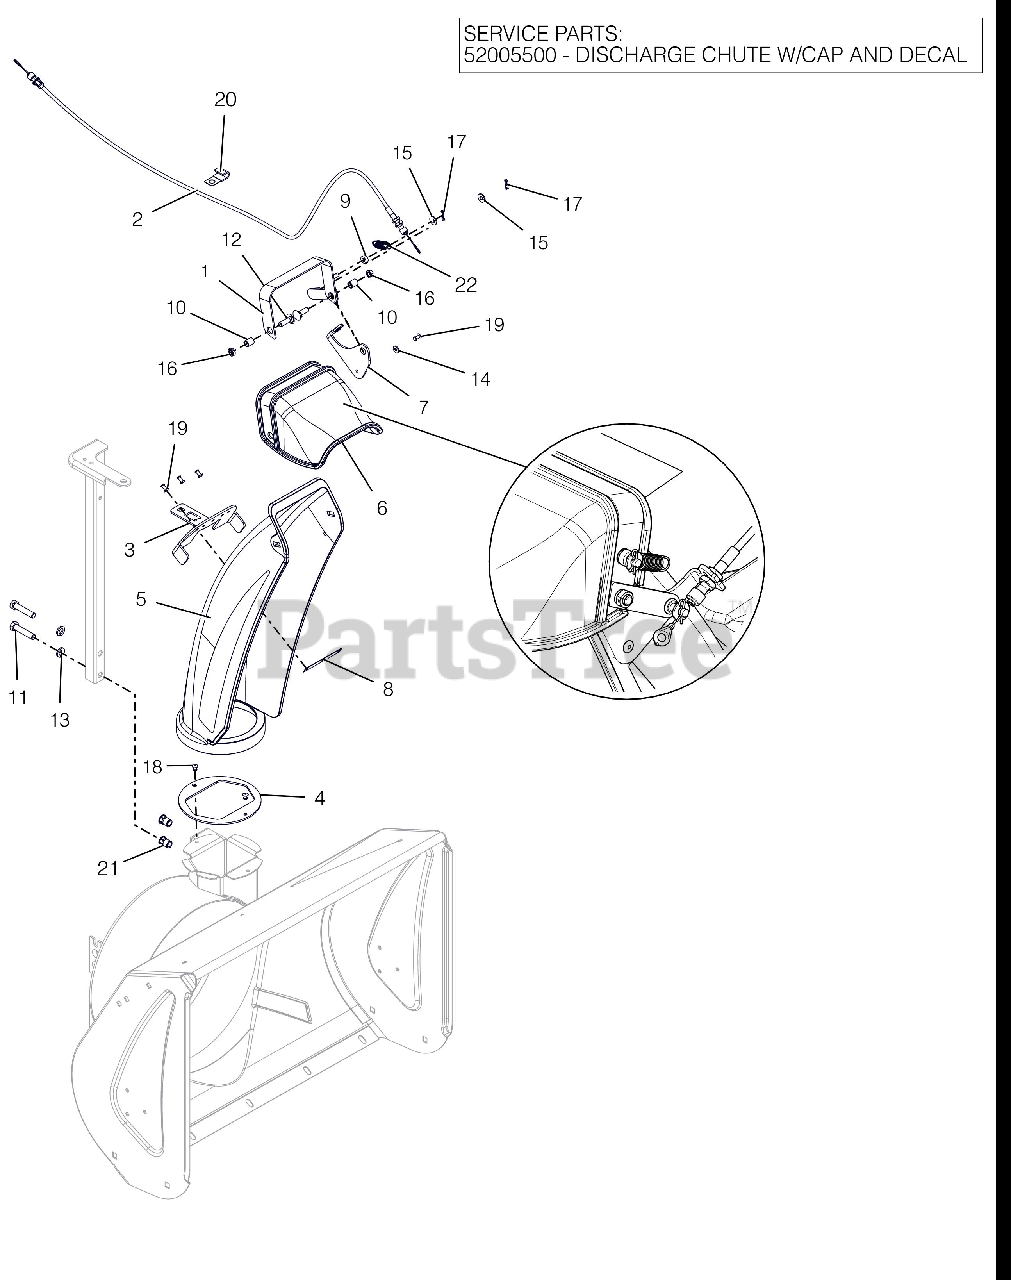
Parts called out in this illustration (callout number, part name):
1	WELDMENT, DEFLECTOR CAP SNOTEK
2	CABLE, DEFLECTOR CAP SNO-TEK
3	CHUTE MOUNT BRACKET
4	BAFFLE, COMPACT DISCHARGE
5	CHUTE, PLASTIC DISCHARGE LONG
5	CHUTE, REMOTE DISCHARGE W/CAP
6	CAP,PLASTIC - SNOTEK (W/DECAL)
7	BRACKET, CABLE ANCHOR SNOTEK
8	PLATE,CHUTE MOUNT BACKING
9	BSHG-SLV .265X.500X.219
10	BSHG-SLV .330X.455X.550
11	@BLT-HEX .38-16X1.75 GR5 YWZC
12	BLT,RNHDRECSHNK .31-18X1.00
13	@WSHR-LK .38X.094 REG YWZC
14	WSHR-FL-STL .196X.500X.06 YZ
15	@WSHR-FL-STL.281X.62X.065 YWZC
16	@NUT-LK-CTR-JAM .31-18 YWZC
17	PIN-HAIR INT .06X.18X.77
18	RVT-POP .187 YZ
19	RIVET, #66 STEEL POP PD BLACK
20	J-CLAMP
21	NUT, THREADED INSERT .38-16
22	SPRG, TENSION .052X.520X1.74
